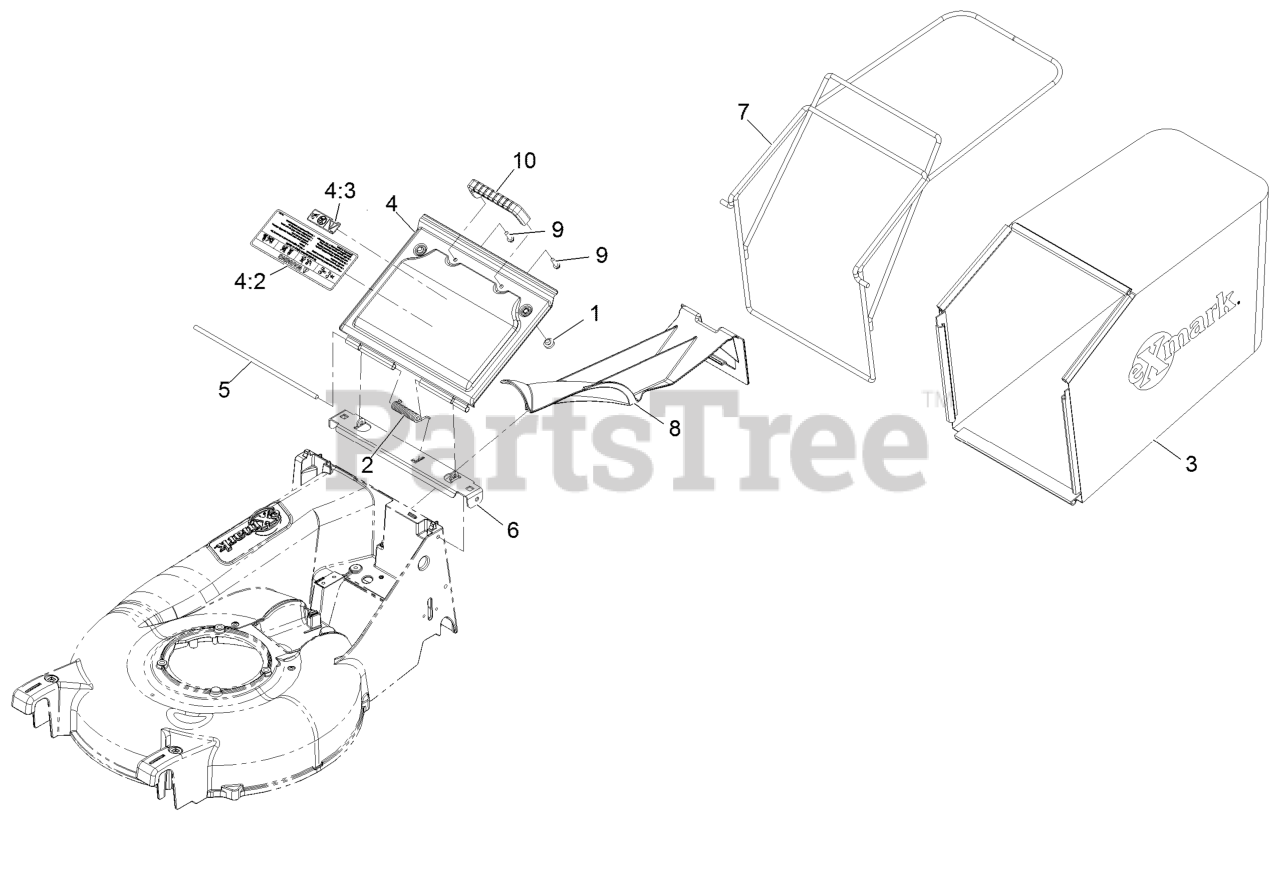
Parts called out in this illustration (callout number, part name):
2	SPRING-TORSION,COVER
3	BAG,GRASS P21
4	DOOR W/DECAL
4:2	DECAL-WARNING DOOR LG
4:3	DECAL-WARNING, BLOCK
5	ROD,DOOR PIVOT
6	BRACKET-DOOR P21
7	WLD,BAG FRAME
8	PLUG,MULCH
9	SCREW-HWH
10	HANDLE-DOOR
